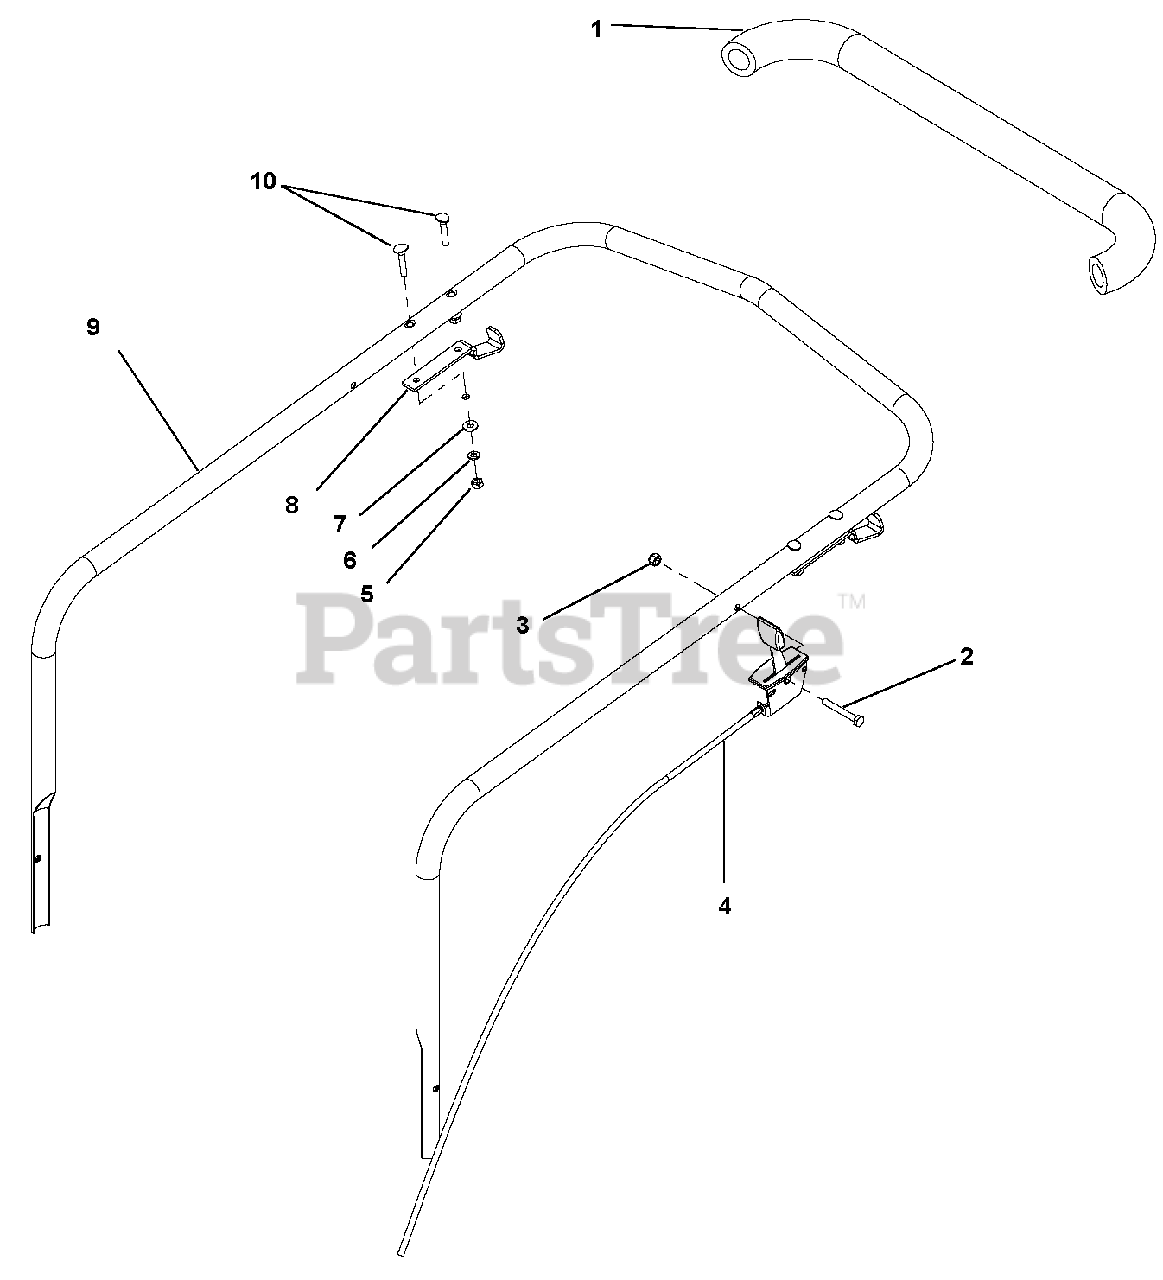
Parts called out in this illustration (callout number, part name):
1	Sleeve, Handle
2	Bolt, Hex .25-20 X 2.00
3	Nut, Locking, Nylon .250-20
4	Throttle, APV B/S Engine
5	Nu, Hex .25-20
6	Washer, Locking .25 X .062 Regular
7	Washer, Flat, Steel .281 X .62 X .065
8	APV Bag Holder
9	APV Upper Handle
10	Bolt, Cont. Head 1/4-20 X 1.50
